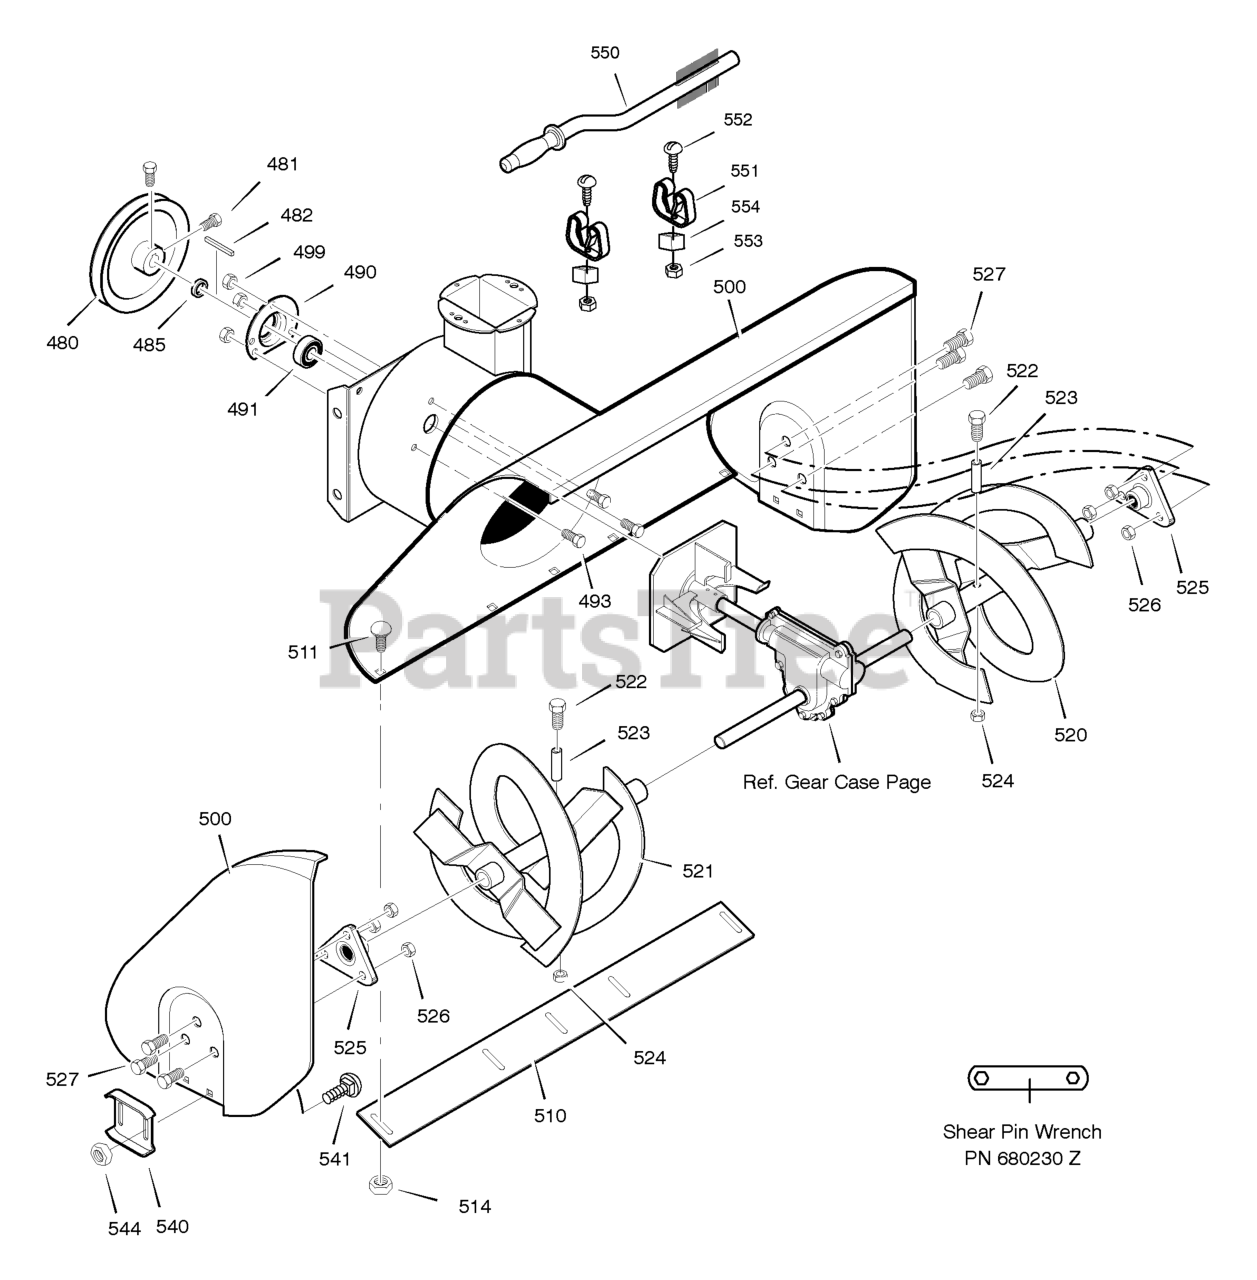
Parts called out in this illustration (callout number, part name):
480	PULLEY, 4L 6.12X .67
481	SCREW, 5/16-18 x 0.63
482	KEY, SQUARE 3/16 X 3/4
485	SPACER, FRICTION PULLEY
490	RETAINER, BALL BRNG
491	BEARING, BALL
493	BOLT, HEX 5/16-18X .50
499	NUT, 5/16-18 HEXWDFLLK
500	HOUSING, ASSY
510	BLADE, SCRAPER 24"
511	BOLT, 5/16-18x0.62
514	NUT, 5/16-18
520	AUGER, ASSY, LH
521	AUGER, ASSY, RH
522	SCREW, 1/4-20X1.75
523	SPACER, SLEEVE
524	NUT, 1/4-20
525	BEARING, FLANGE
526	NUT, 5/16-18
527	SCREW, 5/16-18 x 0.75
540	SKID, HEIGHT ADJUST
541	BOLT, 5/16-18 X .75
544	NUT, 5/16-18
550	BRUSH, CLEANOUT
551	CLIP, RETAINER
552	SCREW
553	NUT
